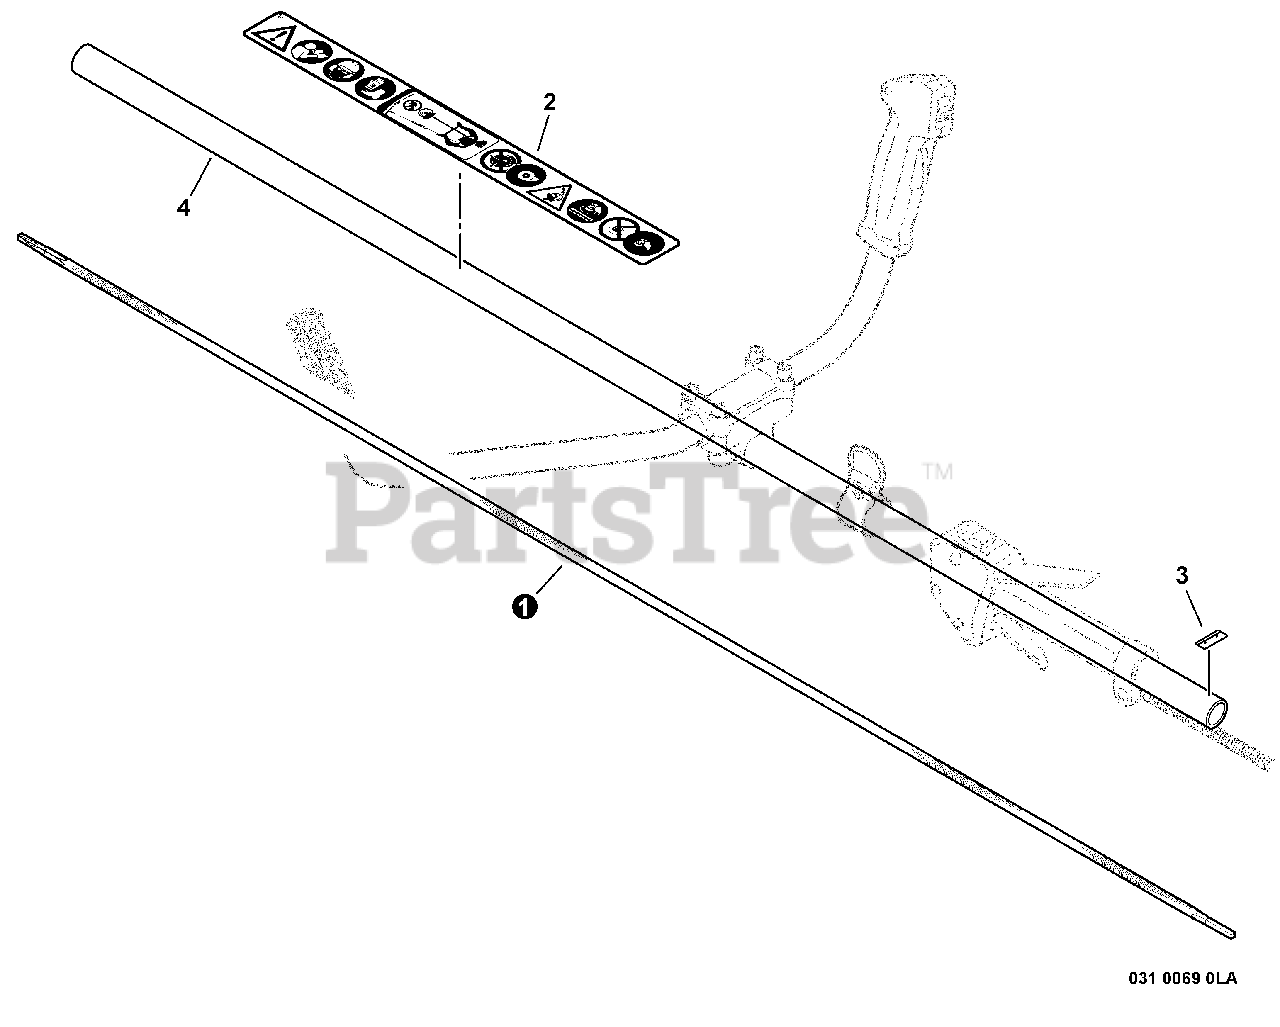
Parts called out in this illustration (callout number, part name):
1	DRIVESHAFT - FLEXIBLE
2	LABEL - CAUTION
3	LABEL - ALIGNMENT
4	MAIN PIPE ASSY
